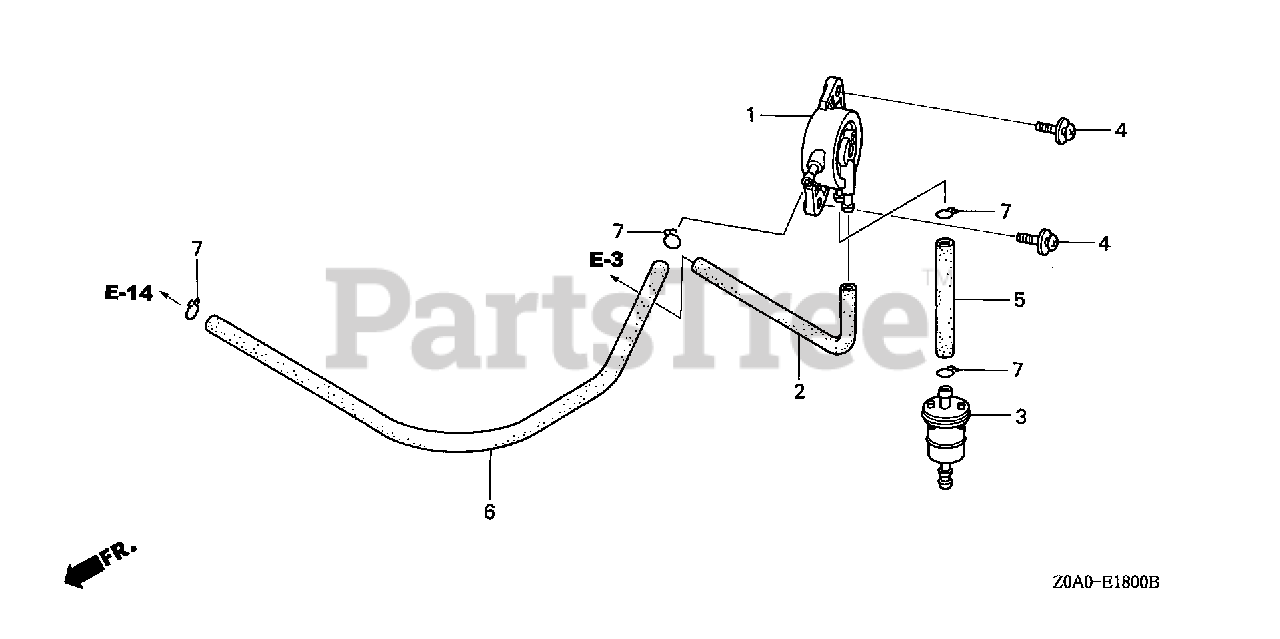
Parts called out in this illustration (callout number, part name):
1	PUMP ASSY., FUEL
2	TUBE, DIAPHRAGM
3	FILTER, FUEL
4	SCREW-WASHER (5X16)
5	BULK HOSE, FUEL (5.5X3000) (Honda Code 5338587). (5.5X150)
6	BULK HOSE, FUEL (5.5X3000) (Honda Code 5338587). (5.5X150)
7	CLIP, TUBE (B10)
